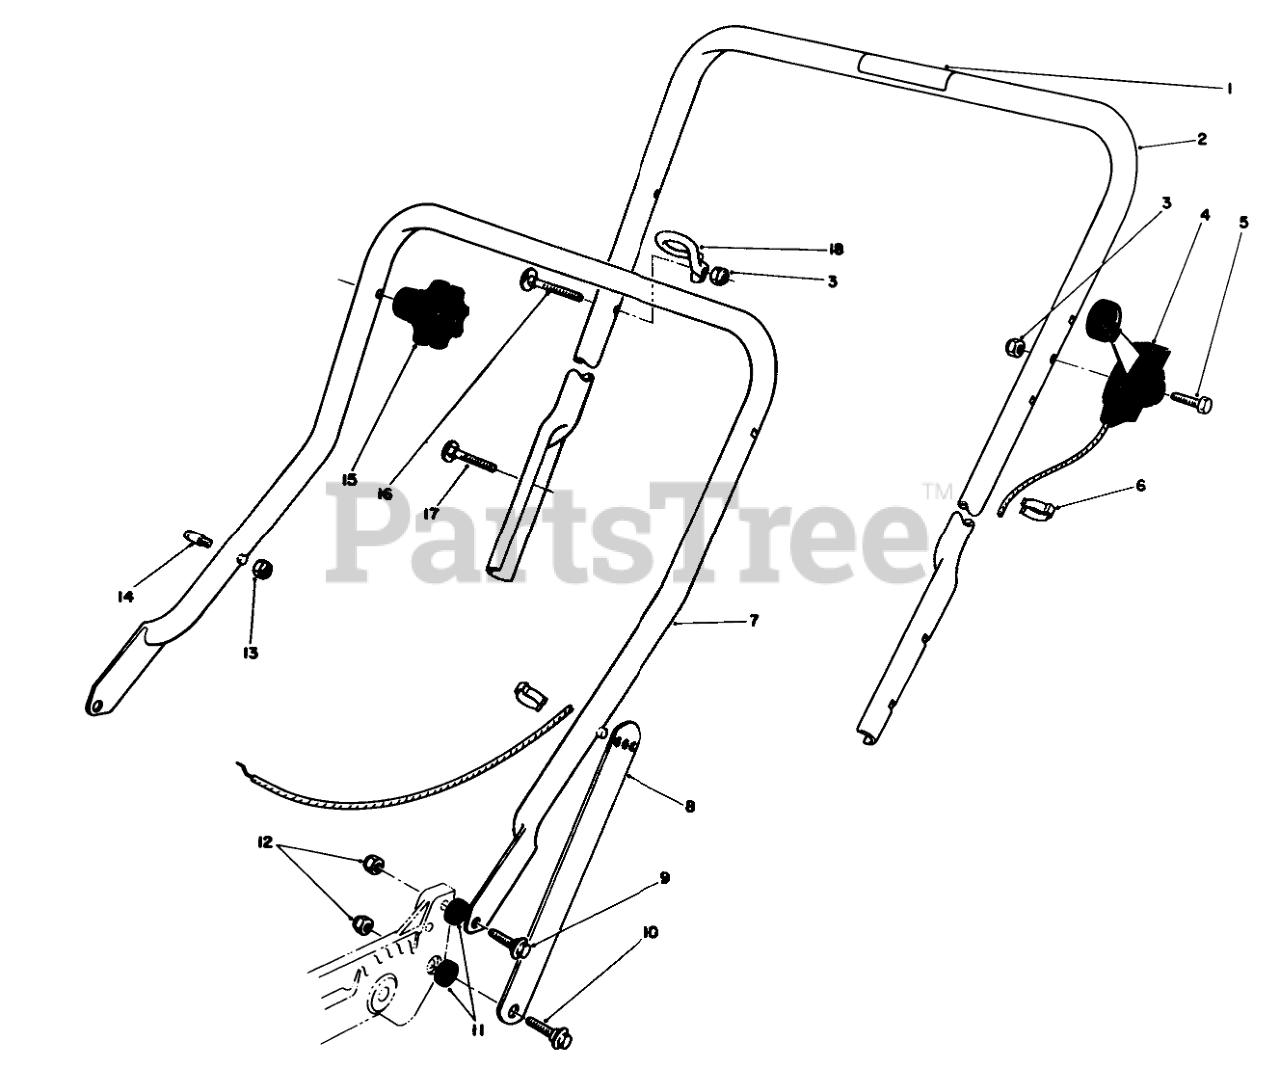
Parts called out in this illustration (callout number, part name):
1	Decal-Danger
2	Handle-Upper (Incl. Ref. #1)
3	NUT-LOCK, NI
4	SERVICE THROTTLE CONTRO
5	SCREW-HH
6	BOWDEN CLIP
7	Handle-Lower
8	Handle Latch
9	SCREW-SHOULDER
10	SCREW-SHOULDER
11	SPACER
12	NUT-LOCK, NI
13	NUT-LOCK, NI
14	HANDLE PIN
15	5/16-18 X 2 HNDLE SCREW
17	HANDLE SCREW
18	Guide
